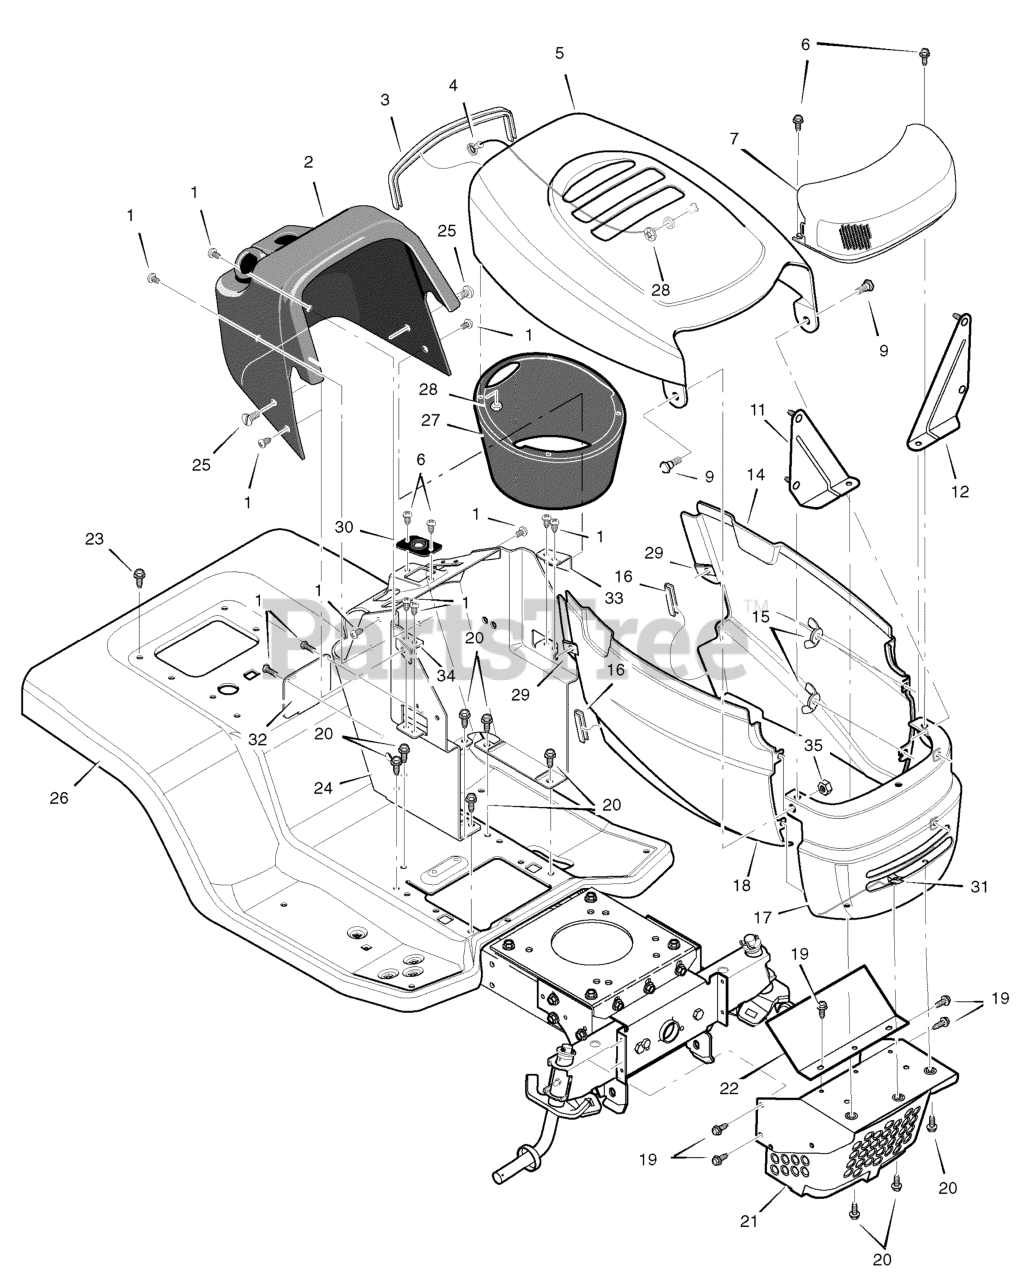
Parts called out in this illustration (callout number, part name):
1	Screw
3	Trim 2.23"
5	Hood Assembly
7	Lens & Reflector Assembly
9	Bolt, Shoulder
11	Brace, Right Grille Assembly
12	Brace, Left Grille Assembly
14	Panel, Left Side
15	Wingnut
16	Trim 0.39"
18	Panel, Right Side
19	Screw
20	Screw
21	Guard Assembly, Muffler
22	Shield, Upper Heat
23	Screw
25	Screw
26	Deck Seat
28	Retainer, Push
30	Bearing, Steering
32	Panel, Access
33	Bracket, Right Console
34	Bracket, Left Console
